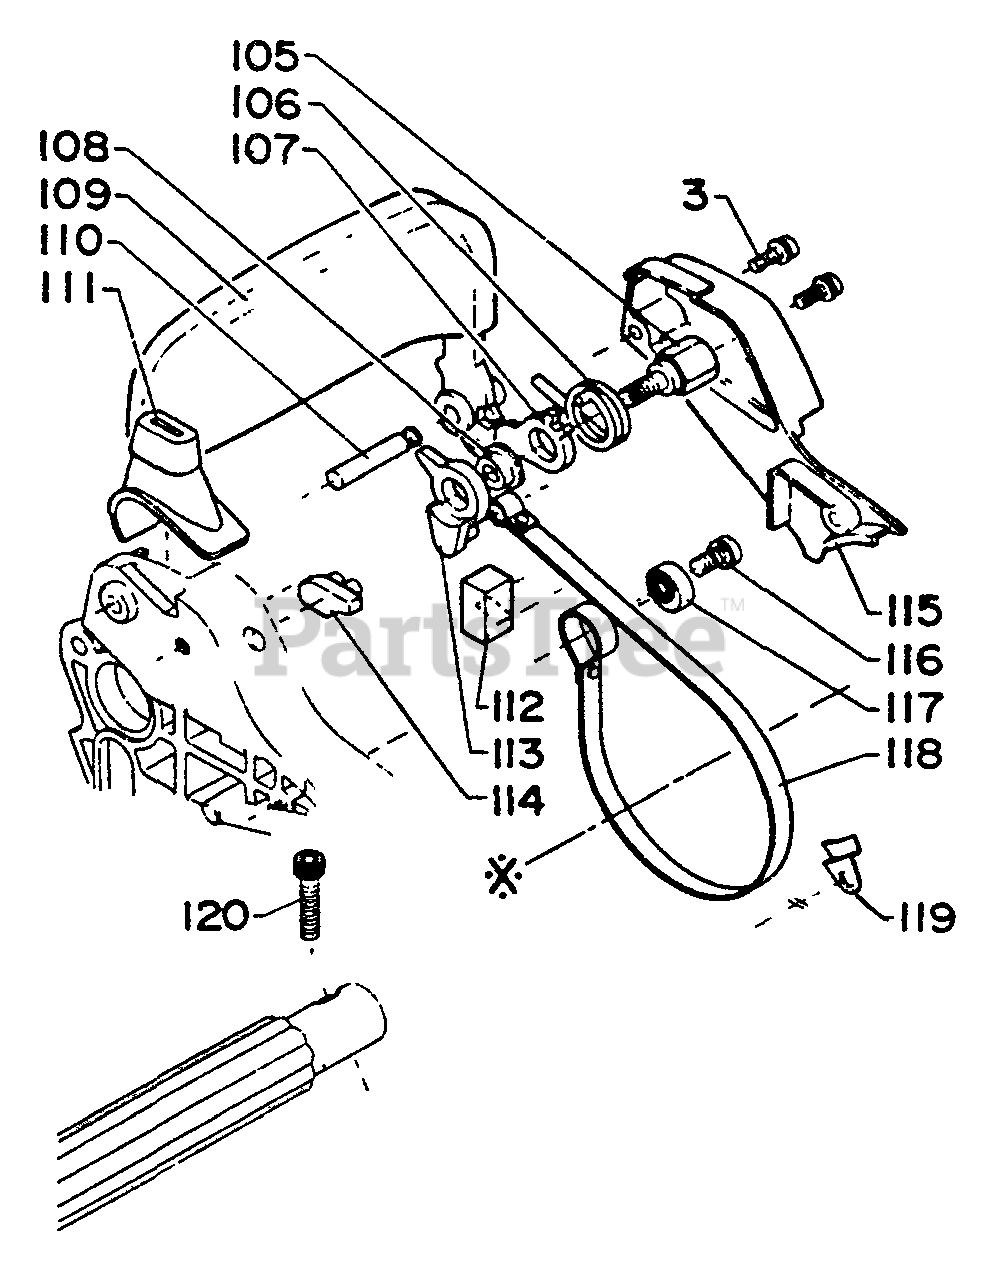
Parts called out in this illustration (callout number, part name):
3	SCREW - 4X12
106	SPRING, RETURN
109	HANDLE, BRAKE
111	COVER, BRAKE
112	SEAL
113	CONNECTOR
114	RESET, BRAKE
115	COVER, BRAKE
116	SCREW - 5X10
117	ADJUSTER, BRAKE BAND
118	BAND, BRAKE
119	RETAINER, BRAKE BAND
120	SCREW - 5X25
